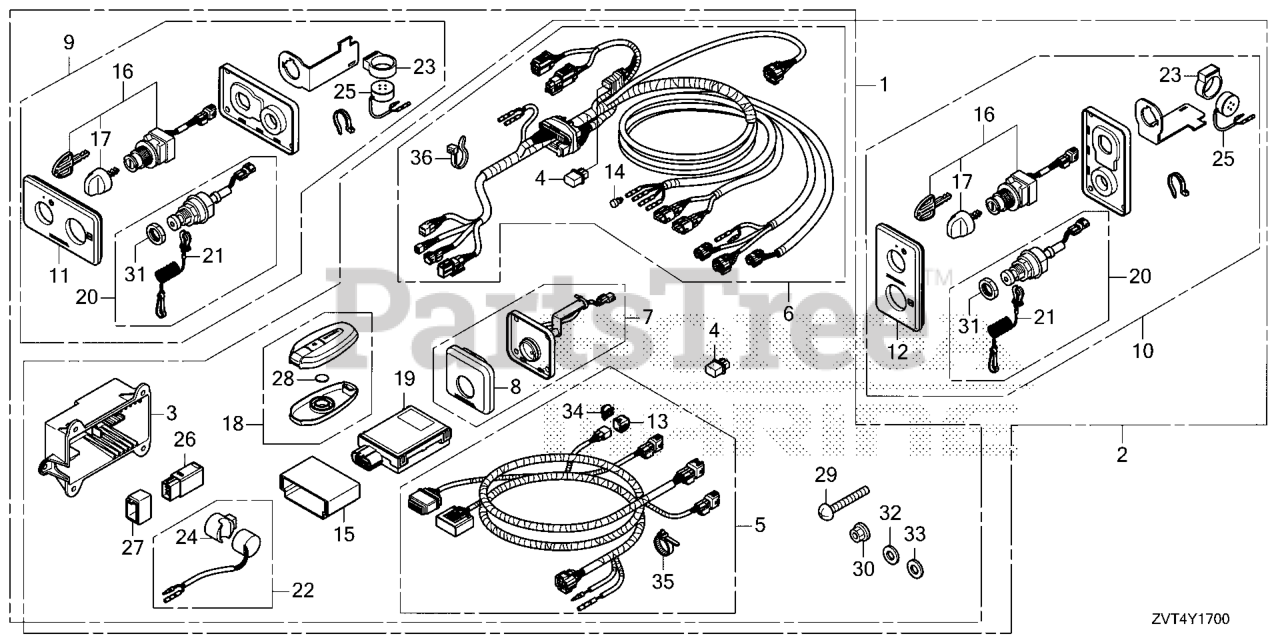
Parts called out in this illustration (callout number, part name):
1	UNIT KIT, SMART KEY
2	UNIT KIT, SMART KEY
3	CASE, CONTROL UNIT (SMART)
4	TERMINATOR ASSY.
5	HARNESS ASSY., SMART KEY CONTROL
6	HARNESS, SMART KEY
7	PANEL ASSY., START STOP (SINGLE)
8	PANEL, START STOP (SINGLE)
9	PANEL ASSY., KEY SWITCH (SMART)
10	PANEL ASSY., KEY SWITCH (SMART)
11	PANEL, KEY SWITCH
12	PANEL, KEY SWITCH
13	CAP, DUMMY (WPC 4P 090 M) (RED)
14	PLUG, CONNECTOR (INNER) (TROLLING CONTROL)
15	SUSPENSION, CONTROL UNIT (SMART)
16	SWITCH ASSY., COMBINATION (SMART)
17	KNOB
18	FOB ASSY. (315MHZ) (NOT AVAILABLE)
19	CONTROL UNIT, SMART (315MHZ)
20	SWITCH ASSY., EMERGENCY STOP
21	WIRE, EMERGENCY
22	BUZZER ASSY., WARNING
23	SUSPENSION, AUDIBLE PILOT
24	SUSPENSION, WARNING BUZZER
25	BUZZER, WARNING
26	RELAY ASSY., MAIN
27	SUSPENSION, RELAY
28	BATTERY (CR2025) (MSDS)
29	SCREW, PAN (5X40) DUAL QTY = (8) (SINGLE)
30	NUT, FLANGE (5MM)
31	NUT
32	WASHER, PLAIN (5MM)
33	WASHER, SPG (5MM)
34	CLIP, CONNECTOR (DARK BROWN)
35	CLIP, HARNESS BAND (145MM) (BLACK)
36	BAND, CABLE (NATURAL)
36	BAND, HARN
